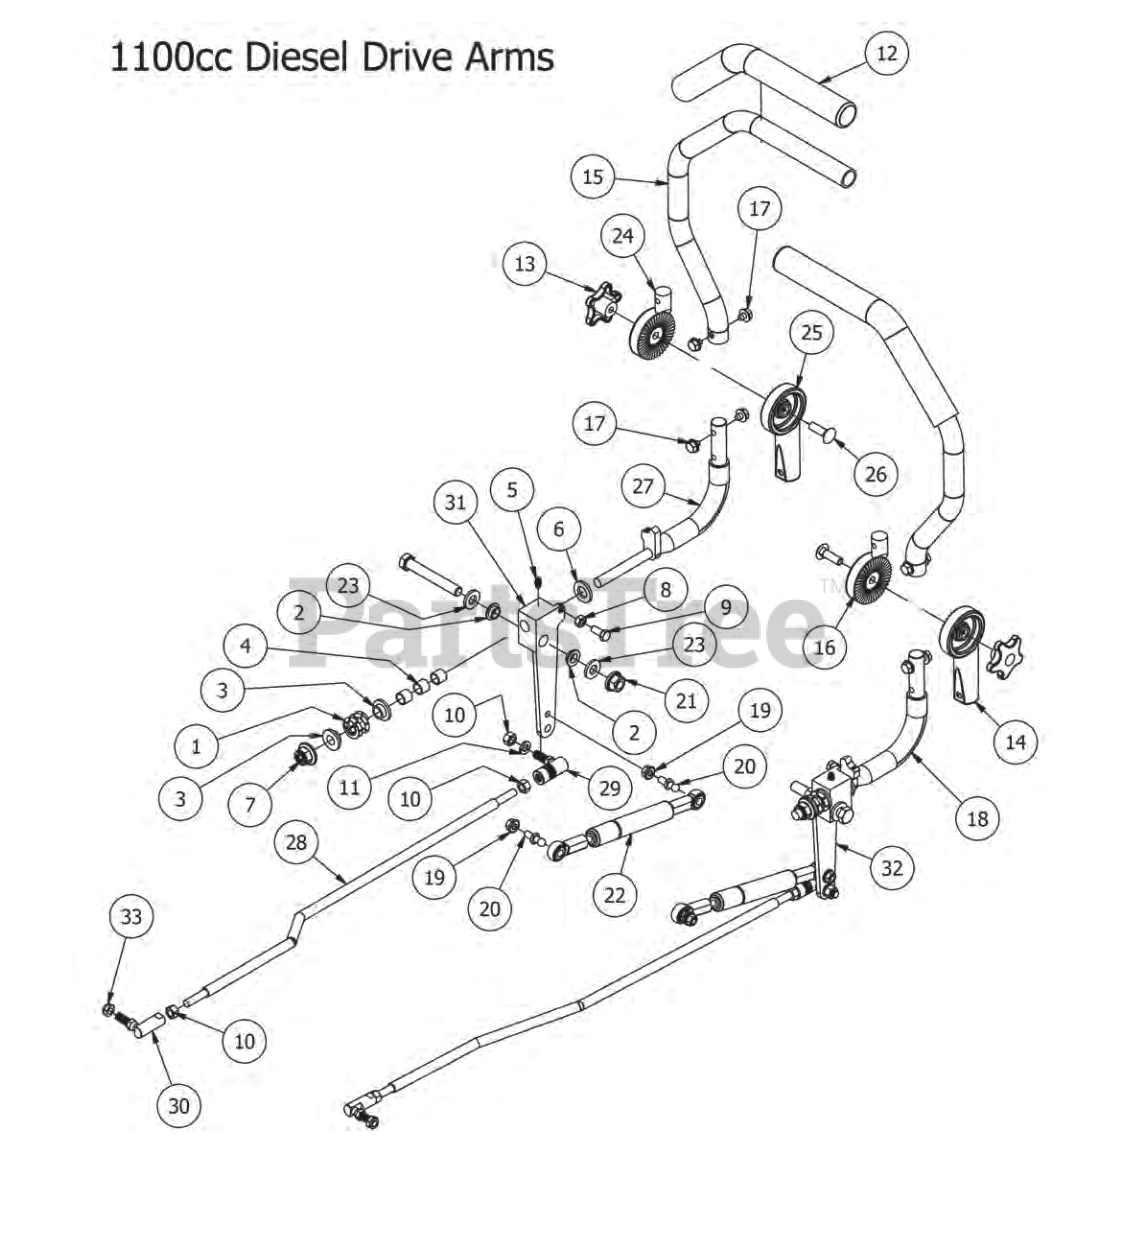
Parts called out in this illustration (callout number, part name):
1	Drive Lever Spring
2	Bushing for 2012 Drive Arms
3	.515 ID Nylon Shoulder Washer
4	.507 ID Nylon Bushing
5	1/4" Press in Grease Fitting
6	.635 ID Plastic Washer
7	1/2-13 Nylon Flange Nut-Orange
9	5/16" x 3/4" Hex Bolt
10	3/8" Fine Threaded Jam Nut
11	3/8" Lock Washer
12	Black Steering Grip
13	Black Knob for Adjustable Steering Arm
14	Lower Adjuster -Steering Arm- Right
15	Upper Tube-Adjustable Steering
16	Upper Adjust Steering Arm- Right
17	5/16-18 1/2 HWH Bolt-Steering
18	Steering Arm Elbow - Right
19	5/16" Flange Nut
20	10mm Damper Ball Stud-Steering
21	1/2-13 Hex Flange (GR.G) ZC
22	Steering Damper
23	.505x1x.125 Oil Impregnated washer
24	Upper adjuster-Steering Arm- Left
25	Lower Adjuster - Steering Arm- Left
26	3/8" x 1 1/4" Carriage Bolt
27	Steering Arm Elbow - Right
28	1100cc Diesel Push Rod
29	Quick Release Ball Joint
30	3/8-24 Ball Joint
31	Drive Arm Lever Housing (Left)
32	Drive Arm Lever Housing Right
33	3/8-24 Nylon Insert jam locknut
